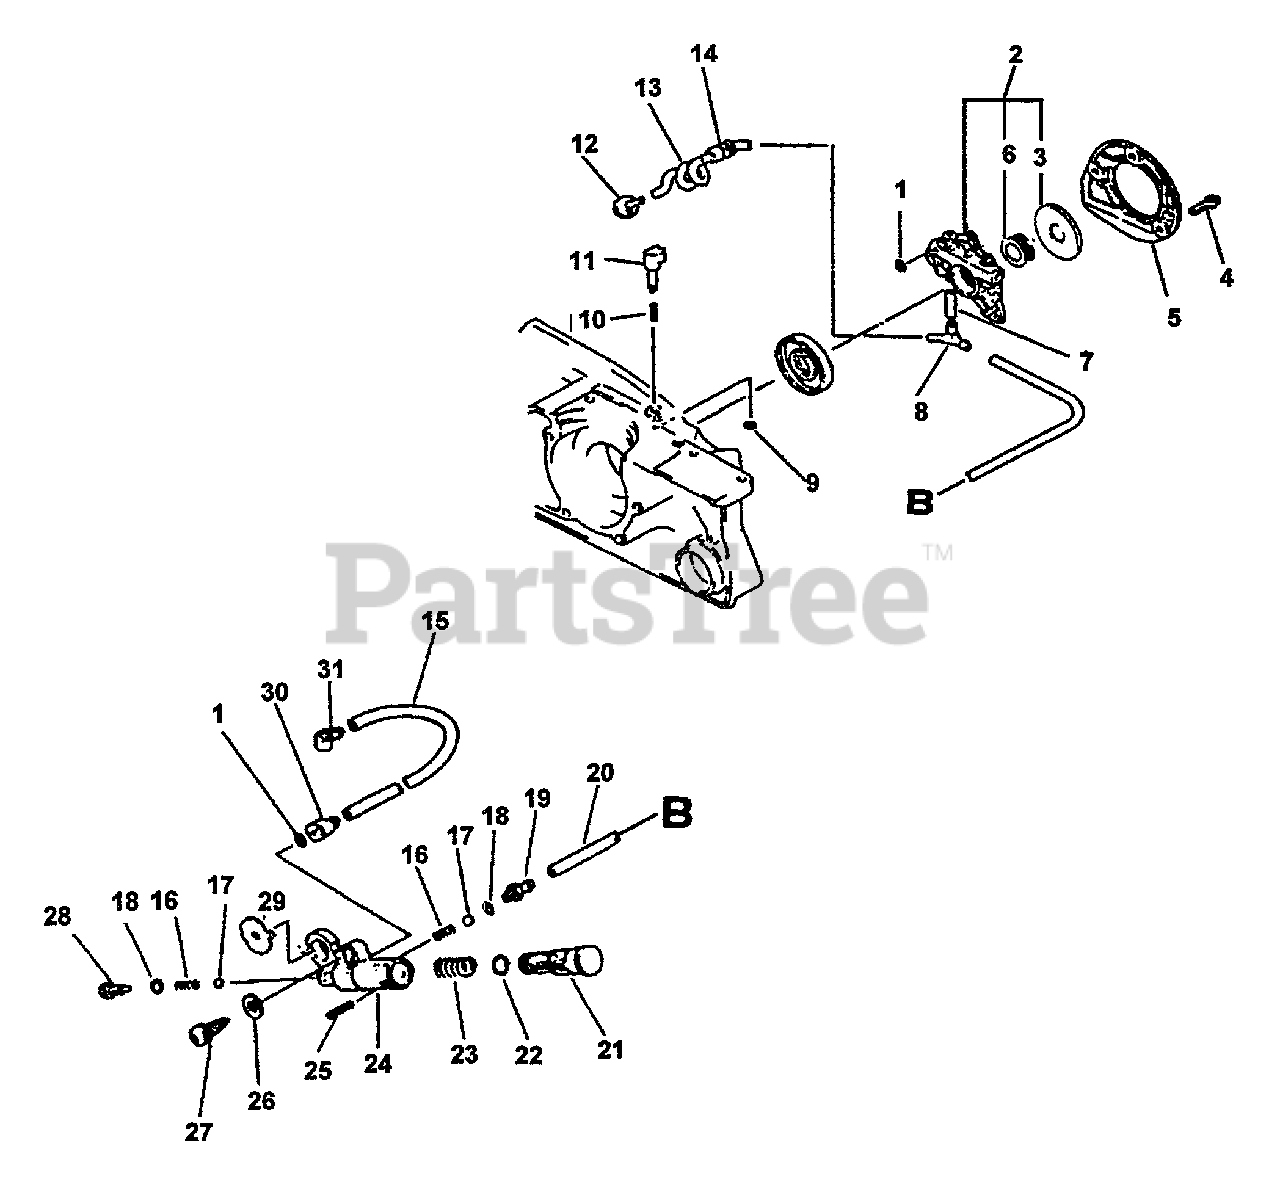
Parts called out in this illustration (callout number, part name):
1	O-RING 3
2	AUTO-OILER KIT
4	BOLT 4×12
5	COVER, OIL PUMP - GRAY
6	GEAR, WORM
7	CONNECTOR, PIPE
8	PIPE, OIL 3×6×20
9	E-RING 3
12	FILTER, OIL
13	PIPE, OIL
15	PIPE 3×6×125 BLACK
16	SPRING, VALVE
17	VALVE, BALL
19	CONNECTOR, PIPE
20	PIPE, OIL
21	PISTON, OIL PUMP - ORANGE
22	O-RING 7 MM
24	BODY, OIL PUMP
25	PIN, SPRING 2×16
26	WASHER 5.5×12×0.8
27	SCREW - 5×20
28	ADAPTOR, OIL PUMP
29	BRACKET, OIL PUMP
30	CONNECTOR, PIPE
31	CONNECTOR, PIPE
